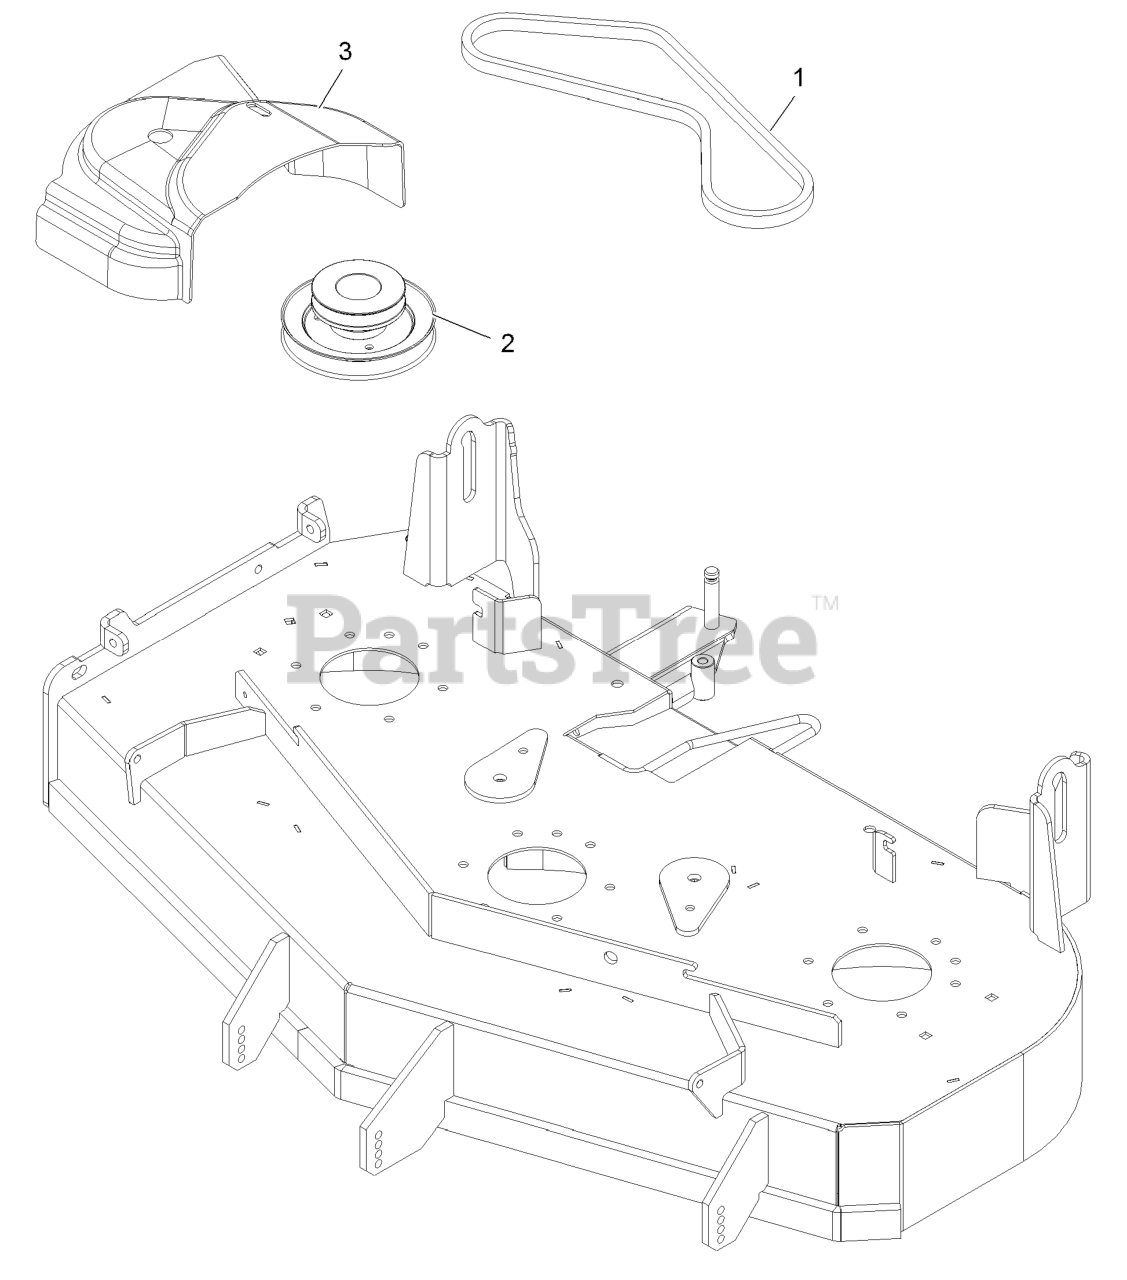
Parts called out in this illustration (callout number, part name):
1	BELT-BLOWER
2	JACKSHAFT-UV DRIVE, 484 S
3	COVER,BELT UV 48
